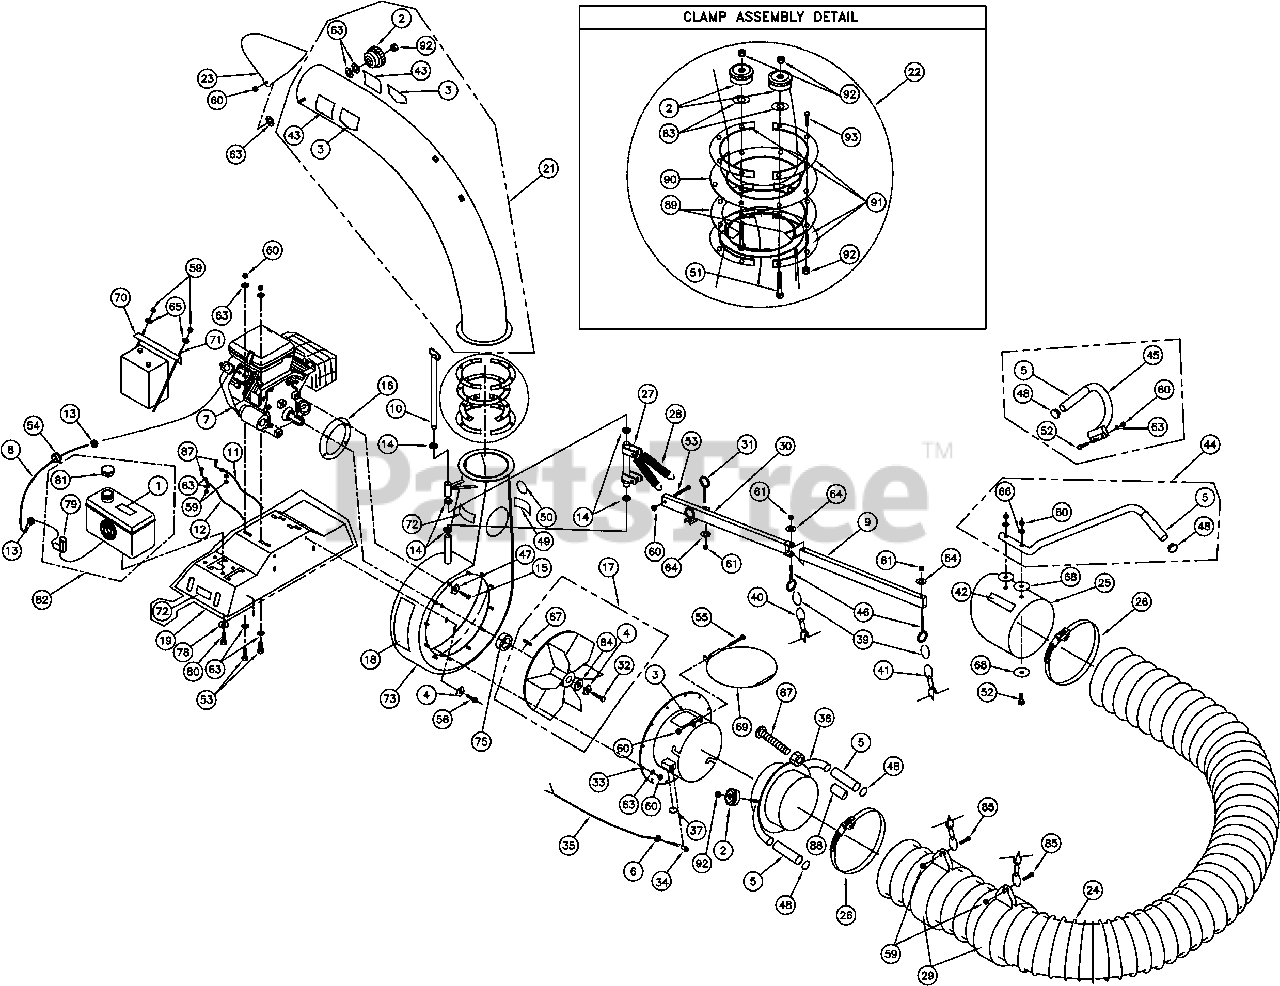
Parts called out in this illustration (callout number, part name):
1	LABEL HOT ENGINE
3	LABEL OPEI WARNING
4	WASHER TWISTED LOCK 3/8"
5	GRIP HANDLE
6	STRAIN RELIEF HEYCO 1244
7	ENGINE 23 HP HORIZ. KOHLER COMMAND PRO
8	LINE FUEL QL
9	TUBE BOOM ARM QL
10	PIN 5/8 X 15.5 QL
11	CABLE BATTERY RED 26"
12	CABLE BATTERY BLACK 10"
13	CLAMP FUEL LINE
14	BUSHING NYLON 0.625
15	SCREWCAP 7/16-14 x 2" GR. 5
16	PLATE RING SPACER QL KOHLER
17	IMPELLER 16" x 1.12" ASSY QL (INCL. 4,32,84)
18	LABEL QL INSTRUCT/WARN
19	BASE ENGINE ASSY QL(INCLUDES 72)
21	ELBOW 8" ASSY QL(INCLUDES 2,3,43)
22	CLAMP ASSEMBLY
23	DEFLECTOR EXHAUST QL
24	HOSE 10" x 10'
25	NOZZLE INTAKE 10" FORMED
26	CLAMP HOSE 10"
27	BOOM HINGE WA QL
28	SPRING BOOM QL
29	BAND HOSE BOOM 10" FORMED
30	ARM BOOM WA QL
31	BOLT EYE 3/8" x 2.5"
32	SCREWCAP 7/16-20X2" GR.8 [TORQUE 60 ft.lb. (81.4Nm)]
33	INTAKE HOUSING ASSY (INCL. 3,6,34,35,37,55,60,63,69)
34	PLUNGE SWITCH
35	HARNESS WIRE ASSY QL23 KO
36	HOSE INTAKE ASSY QL (INCL. 2,38,48,92)
37	PLUG 3/4"
39	LINKGAGE 1/4" CHAIN
40	CHAIN 5 LINKS
41	CHAIN HANG HOSE QL
42	LABEL WARNING NOZZLE
43	LABEL FLYING DEBRIS
44	HANDLE NOZZLE W/ GRIP
45	HANDLE ADJ. NOZZLE W/ GRIP
46	BOLT EYE 3/8" X 5"
47	WASHER LOCK 7/16 TWIST
48	PLUG RD 1"
49	LABEL EAR EYE BREATHE
50	LABEL READ
51	BOLT CARRAIGE 5/16-18 x 2
52	SCREWCAP 5/16-18 x 1 1/2
53	SCREWCAP 5/16-18 x 1 3/4
54	GROMNET 1" x 3/4" I.D.
55	BOLT CARR. 5/16 - 18 x 3 1/2
56	SCREW CAP 3/8 - 16x 1 1/4
58	SCREW SM 1/4 x 3/4
59	NUT LOCK 1/4"-20 HEX Z/P
60	NUT LOCK 5/16-18
61	NUT LOCK 3/8
63	WASHER 5/16 FLAT CUT
64	WASHER FLAT 3/8
65	WASHER 1/4 SAE
66	WASHER 5/16 SAE
67	KEY 1/4 x 2 3/4
68	WASHER 5/16 FENDER
69	DOOR FLAPPER INTAKE QL23
70	BRACKET BATTERY QL
71	ROD BATTERY HOLD DOWN
72	LABEL WARNING SECURE
73	HOUSING ASSY QL
74	TRAY NOZZLE WA QL23KO
75	SPACER - ENGINE
76	WASHER LOCK TWISTED TOOTH
77	BUNGEE CORD BLACK 14"
78	WASHER LOCK TWISTED TOOTH
79	90 DEGREE ELBOW 1/8" NPT MALE X 1/4"
80	SCREWCAP 5/16-18 X 3/4 HCS ZP
81	CAP TANK FUEL 3 GAL
82	TANK FUEL 3 GAL ASSY
83	U-BOLT 3/8" -16 - X 3
84	WASHER PLATE IMPELLER
85	SCREWCAP 1/4-20 x 1 1/2
87	BOLT CARRIAGE 3/4"-10 X 6" ZP
88	TUBE GRIP
89	PLATE CLAMP SPLIT
90	PLATE CLAMP SPACER
91	PLATE CLAMP HALF
92	LOCK NUT 5/16-18 THIN ZP
93	BOLT CARRIAGE 5/16-1 1/4" ZP
